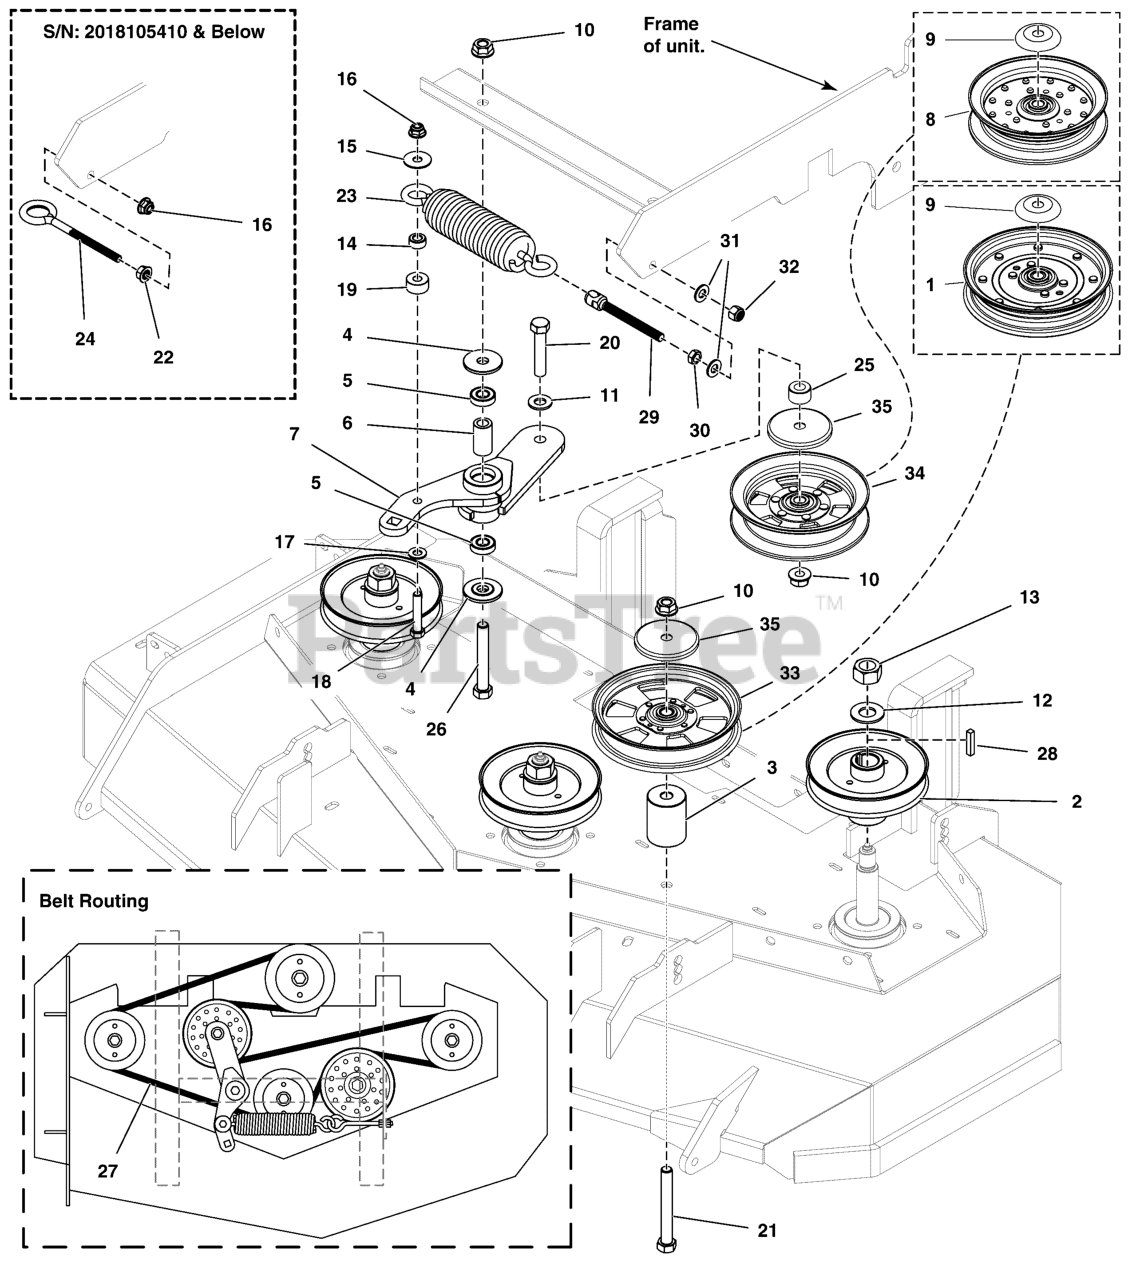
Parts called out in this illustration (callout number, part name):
2	PULLEY, B-SEC, 5.426OB, SPECIAL HUB
3	SPACER, .52 X 1.75 X 2.25, CZ
4	SPACER, IDLER ARM, 1/2, PM
5	BEARING, BALL, AXLE
6	SPACER, .52 X .84 X 1.53, PM
7	WELD, IDLER ARM, MOWER DECK - BLK
9	SHIELD, PULLEY BEARING, CZ
10	NUT, Hex Flange, Nylock, 1/2-13
11	WASHER, 1/2 SAE
12	WASHER, 3/4 BELLEVILLE CL/ZC
13	NUT, 3/4-16 Hex
14	SPACER, .39 X .75 X .38, PM, CZ
15	WASHER, 3/8" Fender
16	NUT, 3/8 - 16 HEX NYLOCK FLANGE
17	WASHER, 3/8 SAE
18	HHCS, 3/8-16 X 2.00, GR5, ZINC/CLEAR
19	SPACER, .39 X 1.00 X .50, PM, CZ
20	BOLT, 1/2-13 X 2-1/2" GD5 CZ
21	BOLT, 1/2-13 X 4" GD5 CZ
22	NUT, 3/8-16 Hex Large Serrated Flange
23	SPRING, DECK, SRSZ1
24	EYE BOLT, 3/8-16 X 6, 3THRD, 1EYE, CZ
25	SPACER, .52 X 1.00 X .63, YZ
26	BOLT, 1/2-13 X 3-1/2, HEX HD, GD5, CZ (SV)
27	BELT, B-SEC, 115.29, ARAMID, WRAPED
28	KEY, 1/4 SQ X 2-1/2
29	SPRING PULLER, 1/2-20, 6.00
30	NUT, 1/2-20 Hex Jam
31	WASHER, 1/2 SAE
32	NUT, Hex, Nylon Lock, 1/2-20
33	PULLEY, FLT IDLR, 6.0 X 1.0 X .50, CZ
34	PULLEY,IDLER,BACKSIDE,NOSEAM 6.25ODX.5ID
35	SHIELD, BEARING, 1/2 ID X 2-7/8 OD, CZ
